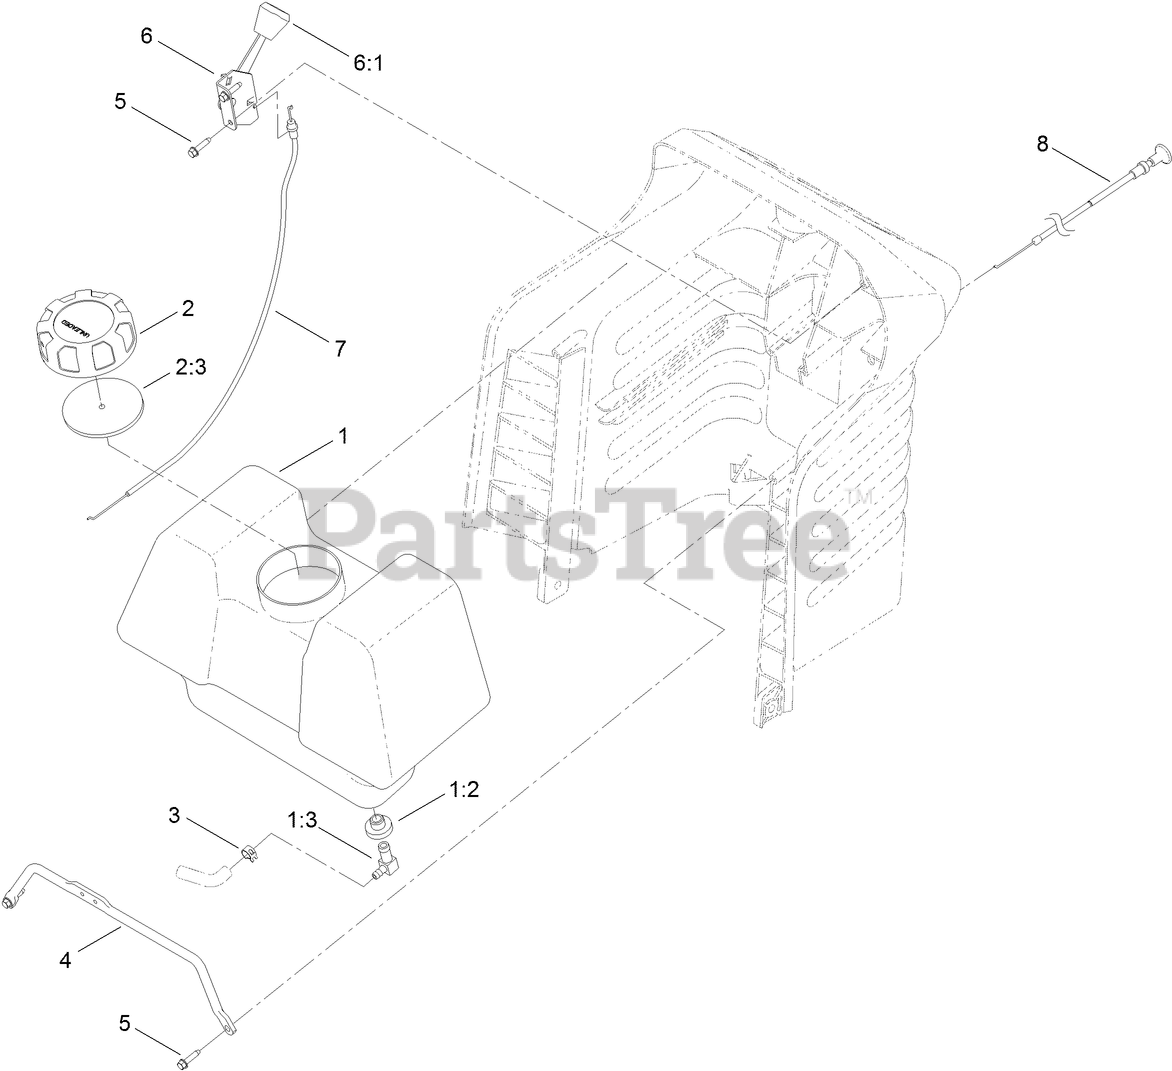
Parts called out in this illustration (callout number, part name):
1	GAS TANK ASM
1:2	BUSHING
1:3	VALVE-FUEL
2	GAS CAP ASM
2:3	GASKET-CAP, GAS
3	CLAMP-HOSE
4	ROD-TANK, GAS
5	SCREW-SPECIAL
6	THROTTLE CONTROL ASM
7	CABLE-THROTTLE
8	CHOKE CONTROL ASM
